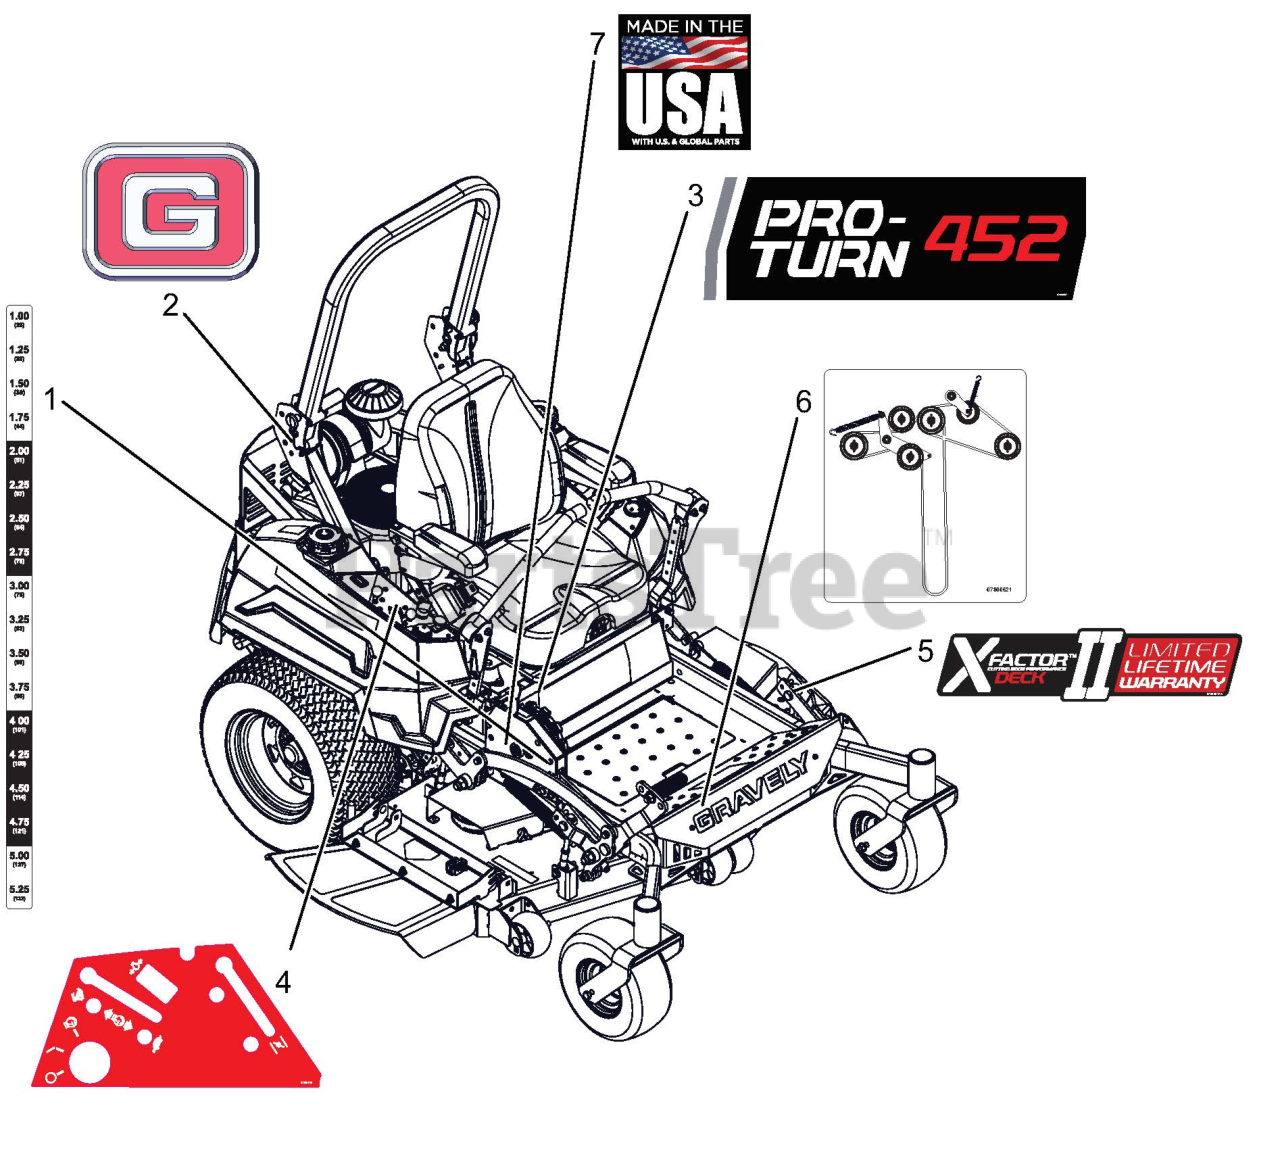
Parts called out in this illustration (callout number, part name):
1	DECAL, PT400 HEIGHT OF CUT
2	DECAL, GRAVELY BRAND
3	DECAL, PRO-TURN 452
4	DECAL, NON-EFI CONTROL PANEL
5	DECAL, X-FACTOR DECK
6	DCL,BELT ROUTE-RH V-SIDE IDLER
7	DECAL, MADE IN USA
